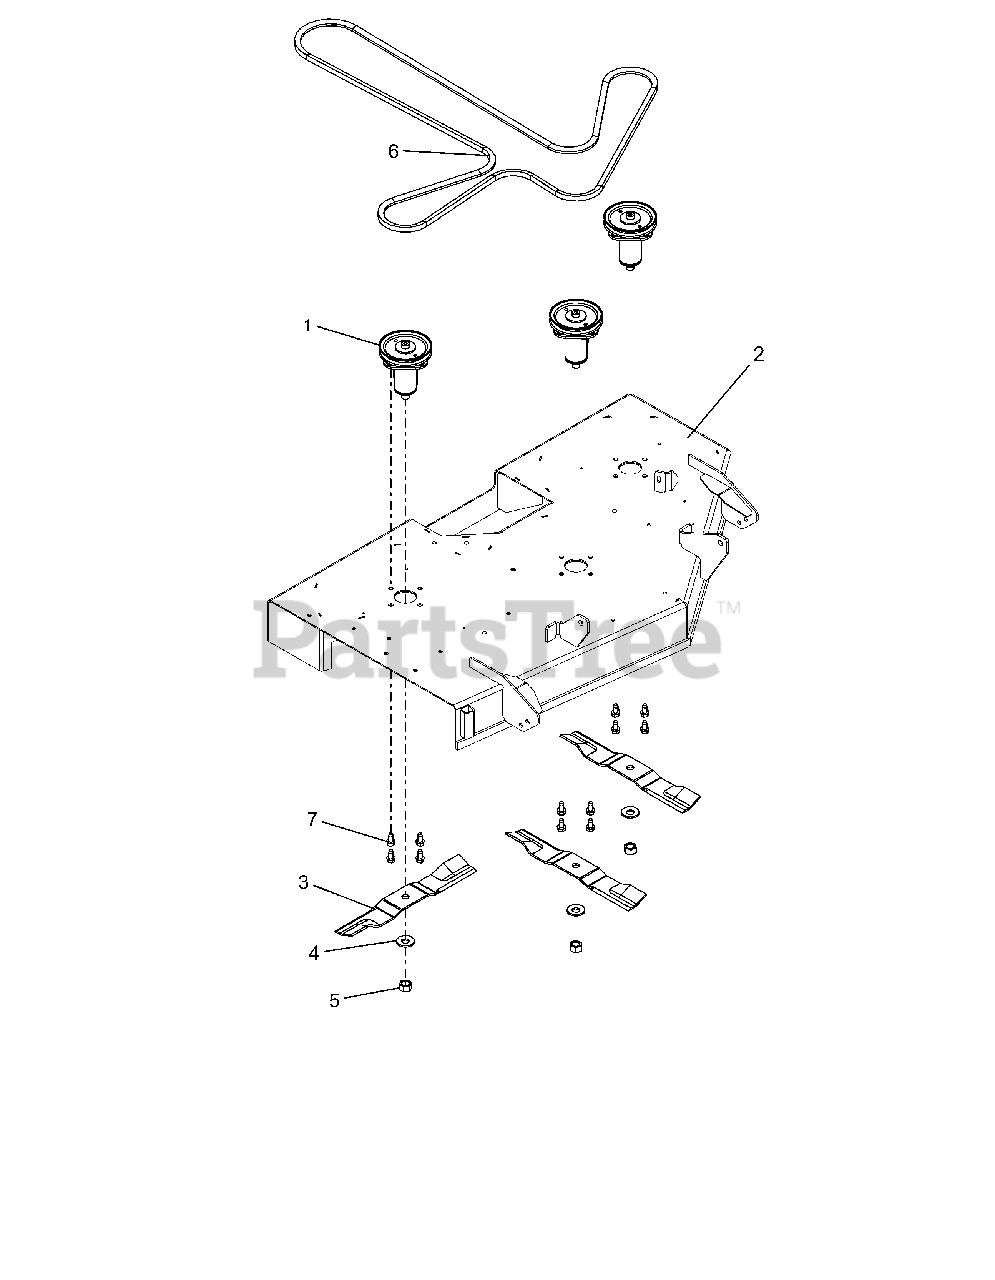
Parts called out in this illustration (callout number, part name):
1	KIT, DECK SPINDLE ASM-IKON-ZTX
2	KIT, 42" GRAVELY DECK W/DECALS
3	BLADE, MOWER 15.00"
4	WSHR-BLVL .669X1.535X.138
5	NUT-HEX .62-18 YWZC
6	V-BELT, 4L-WRAPPED
7	@SCR-TAP .38-16X.75 HWH TR YWZ
